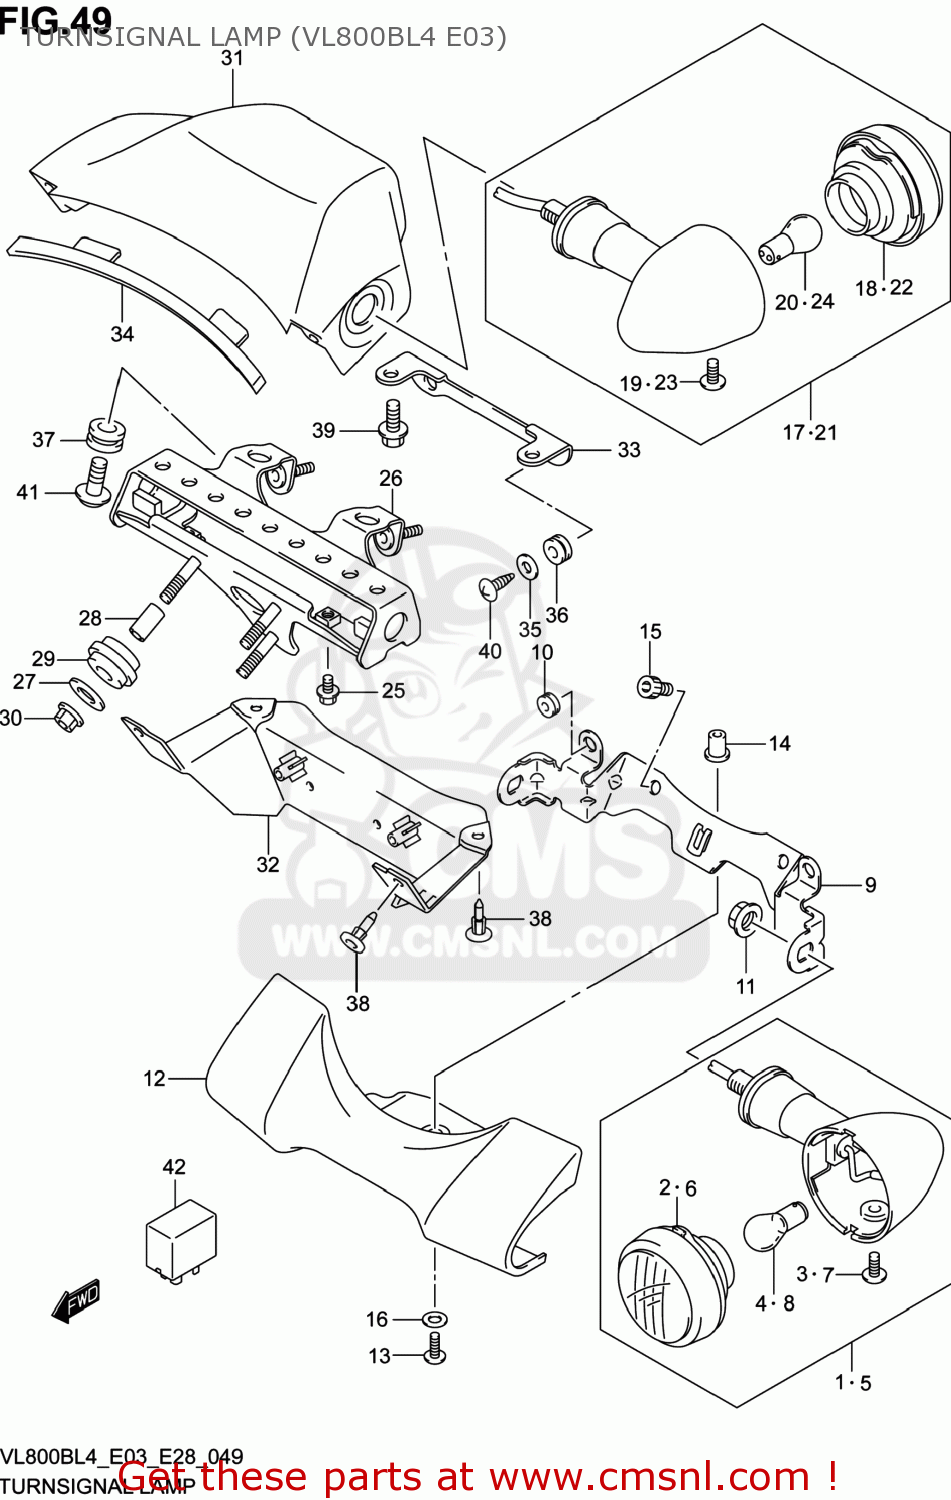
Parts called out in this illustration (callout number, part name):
1	LAMP ASSY,FR TURN SIGNAL,R
2	LENS
3	SCREW(4X10)
4	BULB(12V21/5W)
5	LAMP ASSY,FR TURN SIGNAL,L
6	LENS
7	SCREW(4X10)
8	BULB(12V21/5W)
9	BRACKET
10	CUSHION
11	NUT
12	COVER,FRONT TURNSIGNAL
13	SCREW(5X16)
14	NUT
15	BOLT
16	WASHER(5.5X14X1.2)
17	LAMP ASSY,RR TURNSIGNAL,R
18	LENS
19	SCREW(4X10)
20	BULB(12V21W)
21	LAMP ASSY,RR TURNSIGNAL,L
22	LENS
23	SCREW(4X10)
24	BULB(12V21W)
25	BOLT(6X14)
26	BRACKET,RR TURNSIGNAL
27	WASHER(6.5X20X1.2)
28	SPACER(6.4X10X18)
29	CUSHION
30	NUT
31	COVER,REAR TURNSIGNAL UPPER
32	COVER,RR TURNSIGNAL LWR
33	BRACKET,RR TURNSIGNAL COVER
34	GASKET,RR TURNSIGNAL COVER (NAS)
35	WASHER(4.3X14X0.8)
36	CUSHION
37	CUSHION
38	CLIP(BLACK)
39	BOLT
40	SCREW
41	SCREW
42	RELAY ASSY,TURNSIGNAL LAMP
